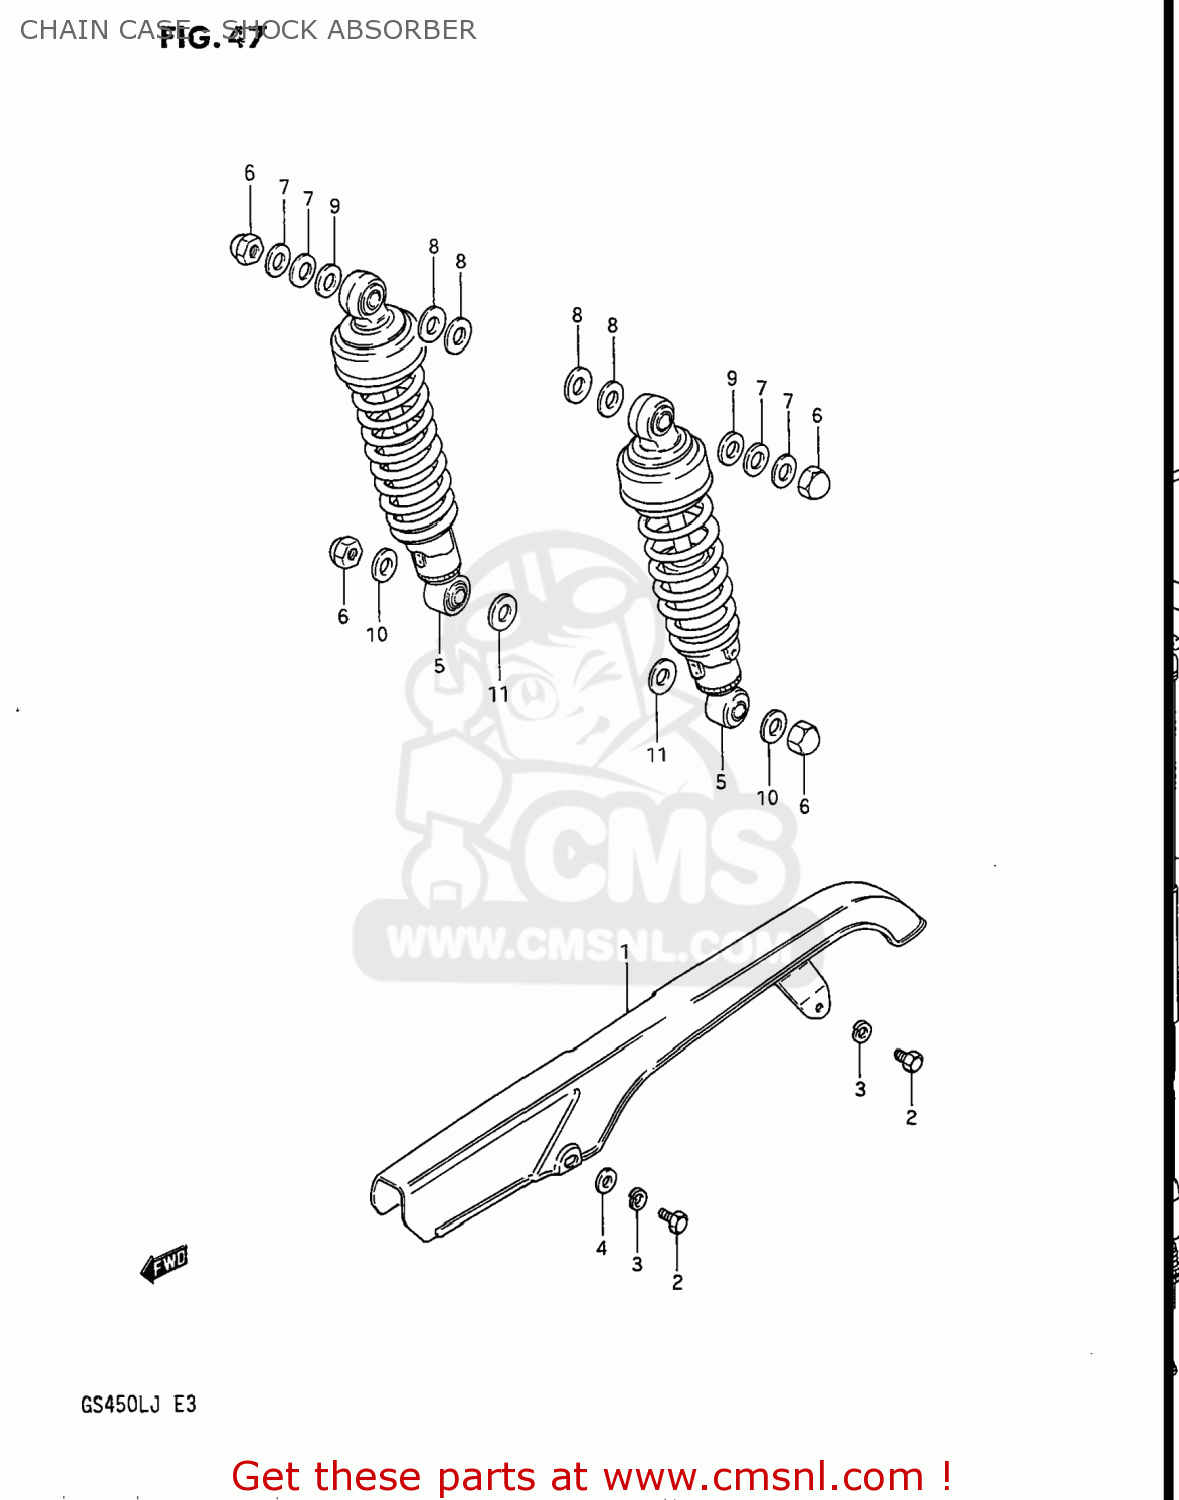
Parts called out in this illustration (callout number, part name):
1	CASE,CHAIN
2	BOLT
3	WASHER,LOCK
4	WASHER
5	ABSORBER ASSY,RR SHOCK
6	NUT, LOWER LH
7	WASHER(10.5X24X3.2)
8	WASHER
9	WASHER (12.5X24X3.2)
10	WASHER
11	WASHER (12.5X24X1.6)
